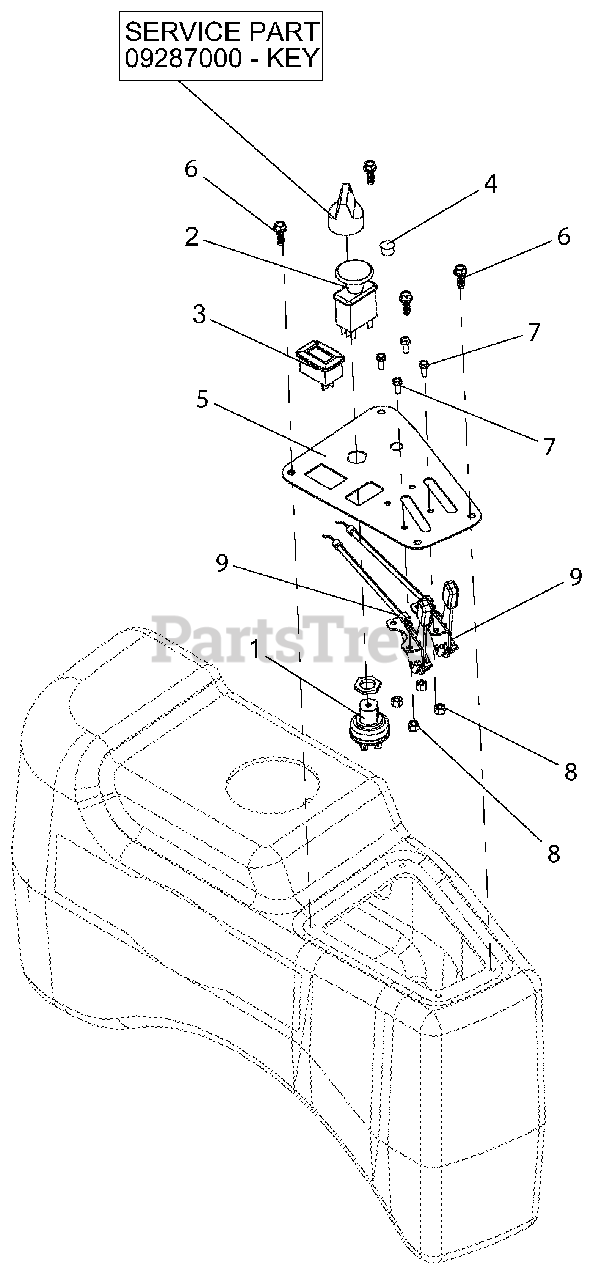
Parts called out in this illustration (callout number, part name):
1	SWITCH, IGNITION
2	SWITCH, CLUTCH
3	METER, HOUR W/MAINTENANCE
4	PLUG, HOLE .50 DIA
5	PANEL, INSTRUMENT-BLACK
6	SCR-PLASTITE .25-10X.75 YWZC
7	@SCR-MCH 10-24X.50 HWH YWZC
8	NUT-LK-NYL #10-24 YWZC
9	CABLE, CONTROL
